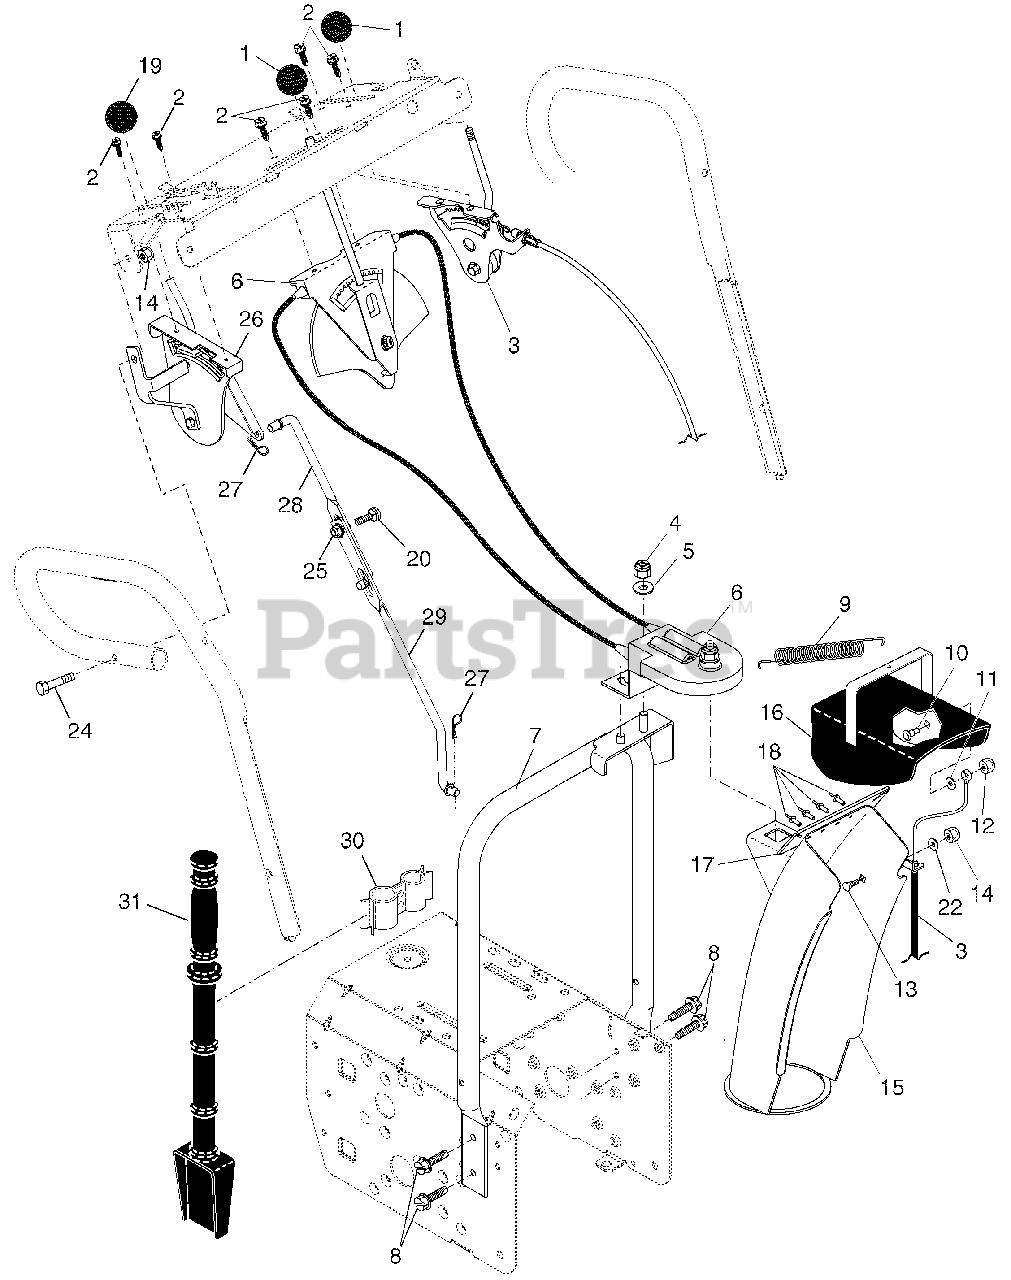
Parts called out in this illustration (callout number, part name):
1	Knob, Lever
2	Screw #10-24 x 5/8
3	Control Assembly, Deflector
4	Nut, Lock 3/8-16
5	Washer, Flat 3/8
6	Control Assembly, Chute Rotater
7	Support, Pivot
8	Screw, Hex Head 5/16-18 x 3/4
9	Spring, Deflector
10	Bolt, Shoulder
11	Washer, Flat 1/4
12	Nut, Lock 1/4-20
13	Bolt, Carriage 5/16-18
14	Nut, Lock 5/16-18
15	Chute Assembly
16	Deflector Assembly
17	Seal, Deflector
18	Rivet, Blind
19	Knob, Speed Control Lever
20	Bolt, Carriage 5/16-18 x 3/4
22	Washer, Flat 5/16
24	Screw, Hex Head 5/16-18 x 1-3/4
25	Nut, Lock 5/16-18
26	Lever Assembly, Speed Control
27	Retainer, Hairpin
28	Rod, Upper, Speed Control
29	Rod, Lower, Speed Control
30	Clamp, Clean-Out Tool
31	Tool, Clean-Out
